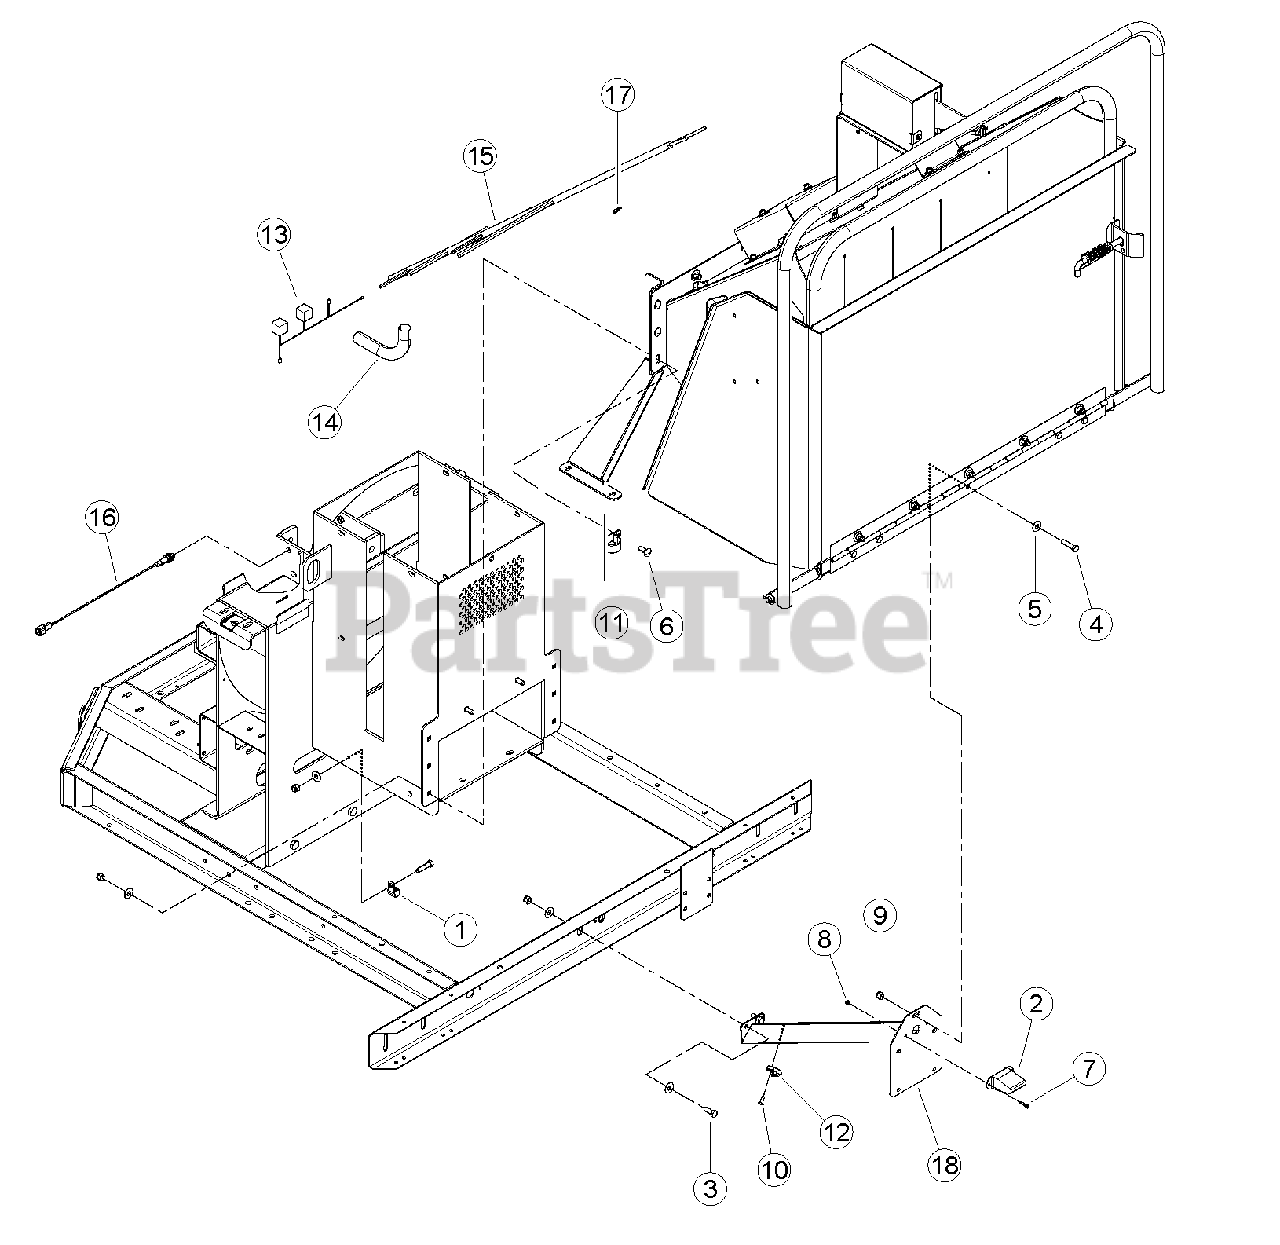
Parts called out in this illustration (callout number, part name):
1	CLAMP, 9/16 COATED
2	LIGHT, LICNESE PLATE
3	BOLT, 3/8 NC X 1 HEX HD GR5 ZP
4	BOLT, 3/8 NC X 1-1/2 HEX HD
5	WASHER, 3/8 FLAT ZP
6	BOLT, 3/8 X 1 CRG
7	SCREW, #10 X 3/4 HEX TAP SC
8	NUT, 8-32 NYLOCK
9	NUT, 3/8 NE NYLOCK ZP
10	RIVET, AL BLIND 1/4 X 3/4 DOME HEAD
11	CLAMP, 1-9/16 COATED
12	CLAMP, CABLE MOUNT
13	HARNESS, CHIPPER SAFETY RELAY
14	SLEEVING, BRAIDED ELECTRICAL HARNESS
15	HARNESS, 6" GAS PLUS 1 CONTROLLER
16	SENSOR, M12 PNP PROXIMITY
17	PLUG, JUMPER HARNESS
18	WELDMENT, CHUTE SUPPORT
